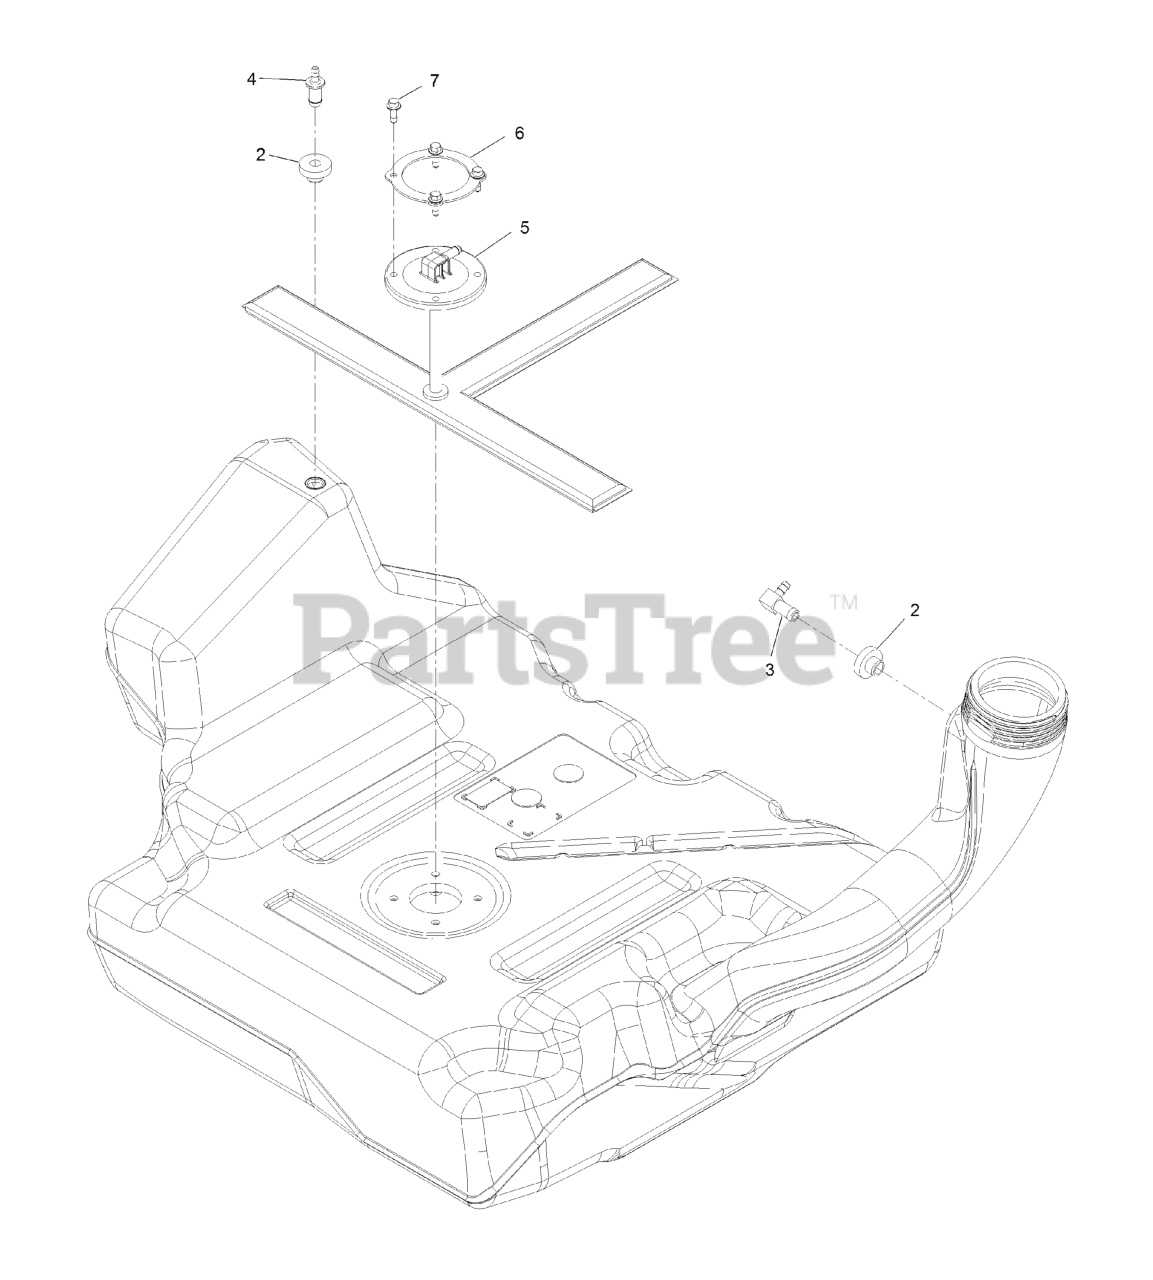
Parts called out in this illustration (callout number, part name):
2	BUSHING
3	FITTING-90 DEG
4	FITTING-ORIFICE, STRAIGHT
5	PICKUP-FUEL
6	RING-RETAINER
